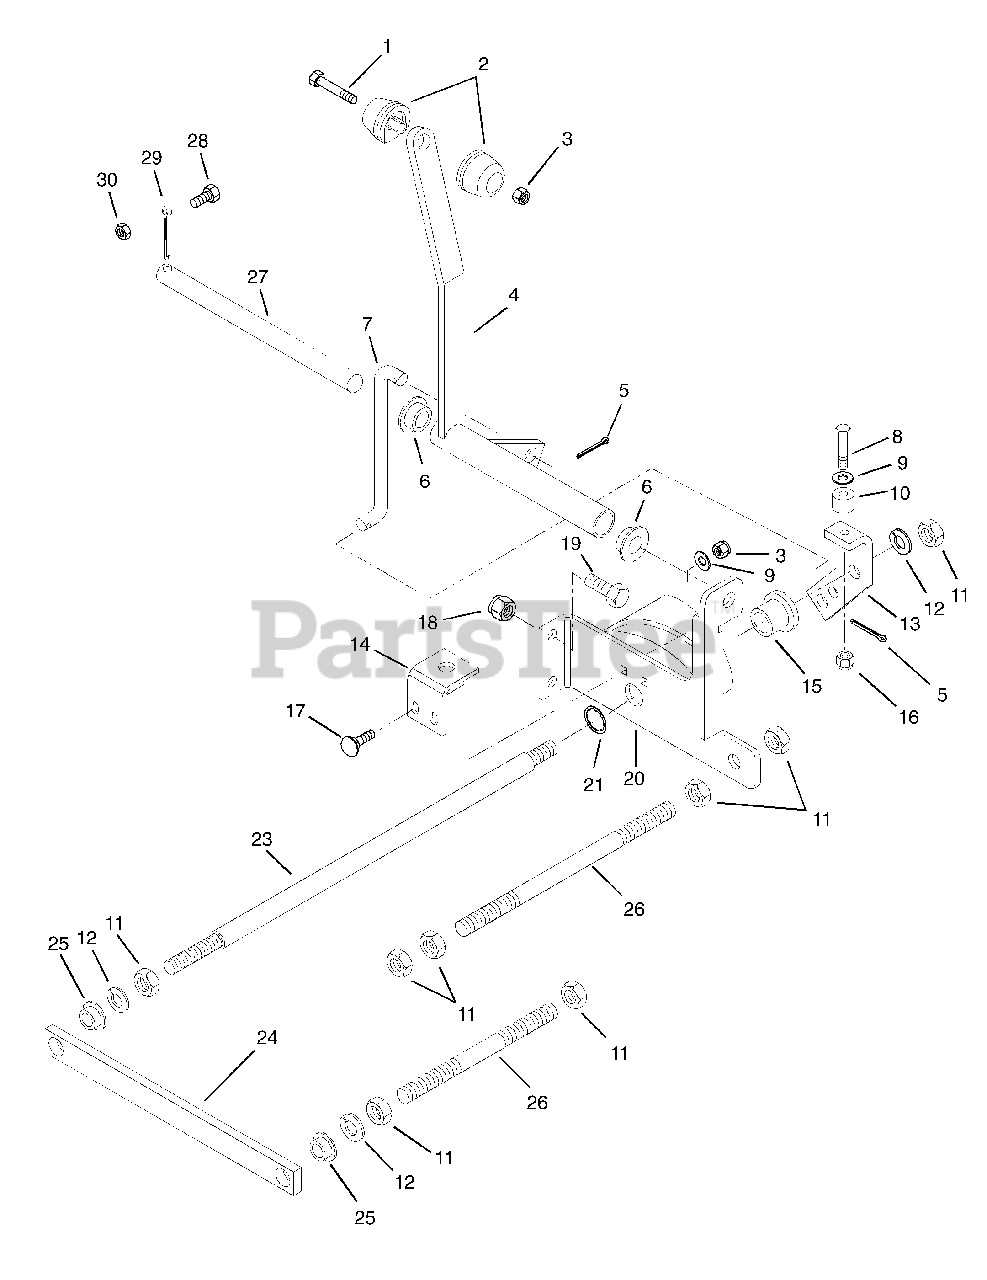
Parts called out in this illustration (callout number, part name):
1	Bolt-Hex .25-20 x 1.50 Grade 5
2	Knob, Control
3	Nut-Locking-Center .25-20
4	Weldment, PTO Control
5	Pin-Cotter .09 x 1.0
6	Bushing-Flange .515 x .750 x .745 x 1.00
7	Rod, PTO
8	Bolt-Hex .25-20 x 1.25 Grade 5
9	Washer-Flat-Steel .281 x .620 x .065
10	Roller-Clutch Cam .250 x .750 x .5625
11	Nut-Hex .50-13
12	Washer-Lock .500 x .151
13	Arm, PTO Clutch Roller
14	Bracket, Interlock
15	Bushing-Flange .762 x 1.00 x .580 x 1.48
16	Nut-Locking-Nylon .25-20
17	Bolt-Round Head Square Neck .25-20 x .75 Grade 5
18	Nut-Locking-Center .38-16
19	Bolt-Hex .38-16 x 1.00 Grade 5
20	Weldment, PTO Bracket
21	Ring-Retaining-External 1.31 x .05
22	Rod, Lift
23	Rod, PTO
24	Spring, PTO
25	Bushing-Flange .500 x .875 x .700
26	Stud, PTO
27	Shaft, Control
28	Bolt-Hex .25-20 x 1.00 Grade 5
29	Pin-Cotter .25 x 2.00
30	Nut-Locking-Center .25-20
